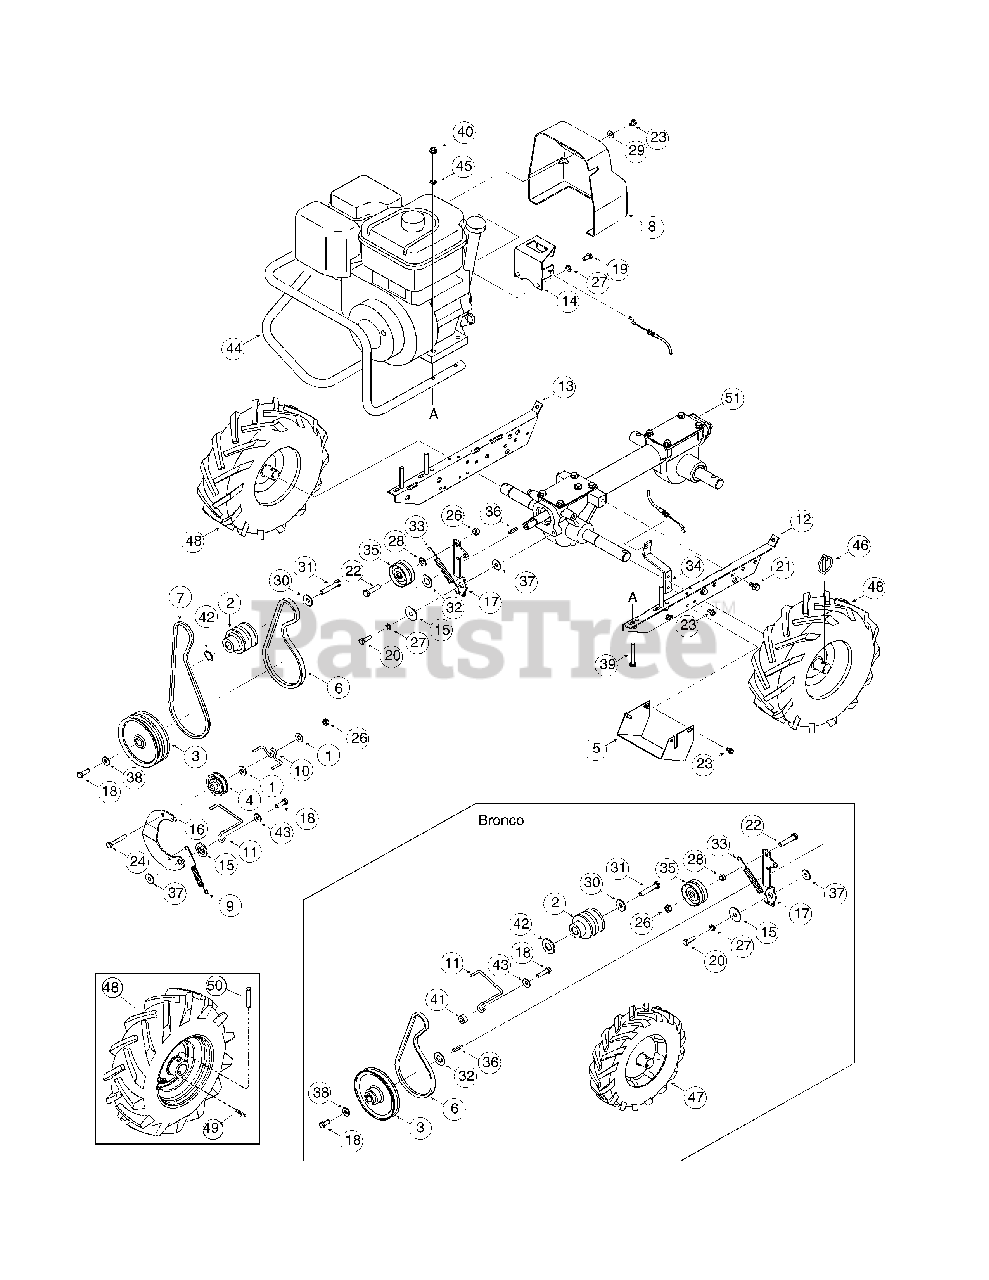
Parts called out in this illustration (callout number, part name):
1	Flat Washer, 5/16
2	Pulley, Engine Drive
3	Transmission Pulley
4	Pulley, Reverse Idler
7	Reverse Drive Belt
8	Belt Cover
9	Reverse Return Spring
10	Belt Guide
11	Belt Guide
12	Engine Bracket, Left
13	Engine Bracket, Right
16	Reverse Idler Arm
18	Hex Hd. Screw, 5/16-24 x 1.25
18	Hex Hd. Screw, 5/16-24 x 1
19	Hex Hd. Screw, 5/16-24 x 5/8
20	Hex Hd. Screw, 5/16-18 x 1
21	Hex Hd. Screw, 5/16-18 x 5/8
22	Hex Hd. Screw, 3/8-16 x 1-3/4
22	Hex Hd. Screw, 3/8-16 x 1.50
23	Screw, Self-Tapping, 1/4-20 x 1/2
24	Hex Hd. Screw, 5/16-18 x 2
25	Lock Nut, 3/8-16
26	Lock Nut, 5/16-18
27	Lock Washer, 5/16
28	Spacer, .380 ID x .625 OD x .21
28	Flat Washer .406 x .812 x .051
29	Flat Washer
30	Bell Washer
31	Hex Hd. Screw, 3/8-24 x 1.50, GR5
32	Support Washer
33	Forward Return Spring
36	Key, 3/16" x 1"
37	Flat Washer
38	Belleville Washer
39	Hex Screw, 5/16-18 x 1.50 Gr5
39	Hex Screw, 5/16-18 x 2-1/4, Gr5
40	Nut, Hex Lock, 5/16-18
41	Spacer, Shoulder
42	Washer, Flat, .75 x 1.5 x .125
42	Flat Washer .786 x 1.000 x .031
43	Bell Washer
45	Nut, Speed, 5/16-18
46	Klik Pin
47	Complete Wheel Assembly 10 x 2.75
48	Complete Wheel Assembly 13x 5 x 6
49	Cotter Pin
50	Clevis Pin
51	Transmission Assembly
